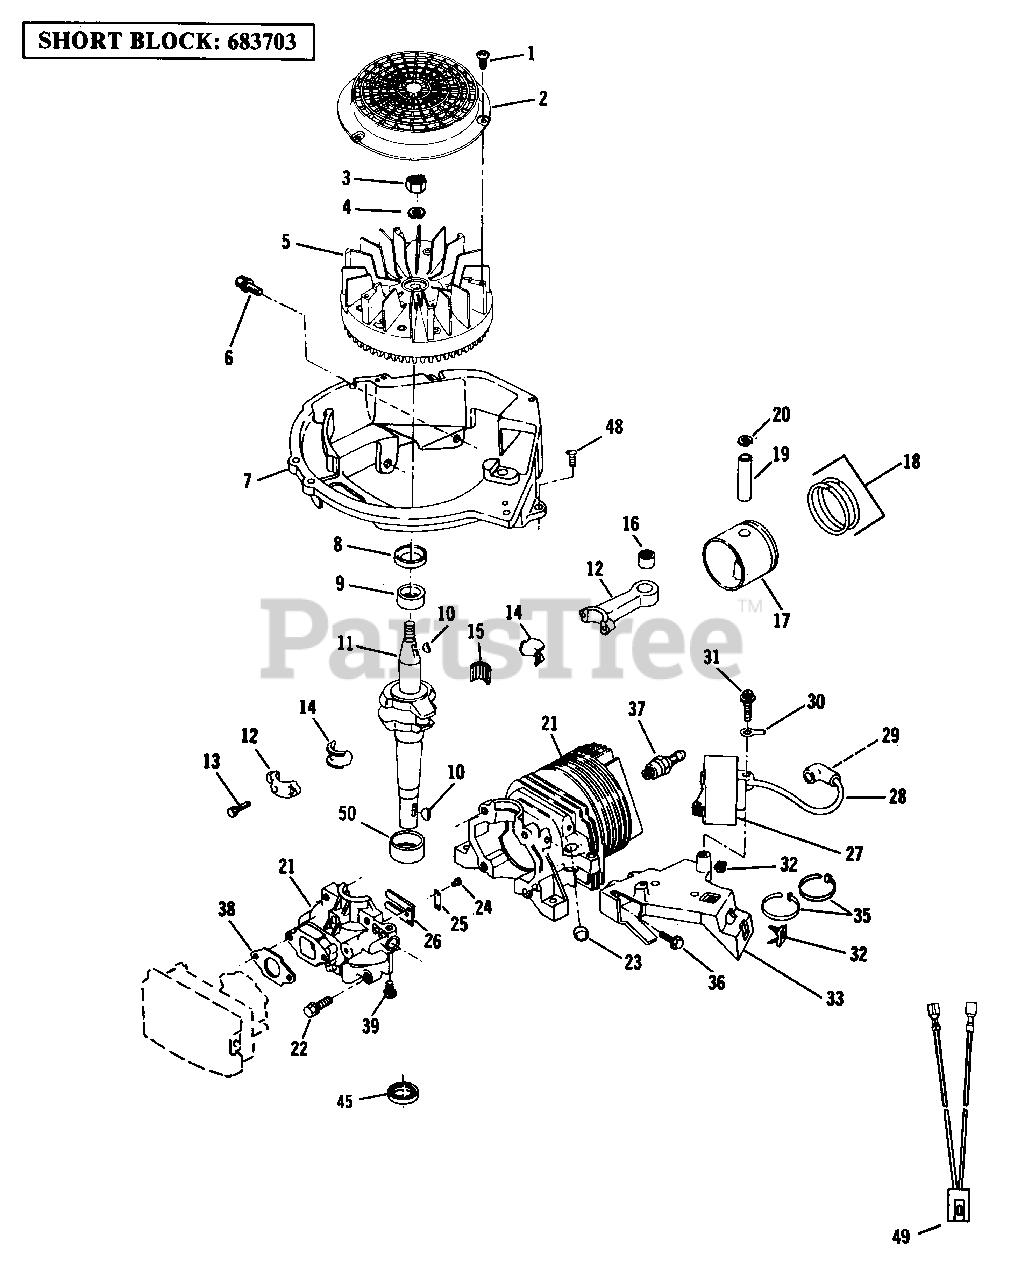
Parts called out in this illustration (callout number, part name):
1	Screw-Flywheel Screen
2	Screen-Flywheel
3	Nut-Flywheel
4	Lockwasher
5	Flywheel Assembly
6	Screw
7	Base-Shroud
8	Oil Seal-Upper
9	Bearing-Upper
10	Key-Flywheel and Clutch
11	Crankshaft
12	Connecting Rod Assembly
13	Screw Lever
14	Liner-Split
15	Needle Bearing Set
16	Bearing Assembly
17	Piston and Ring Set
18	Ring Set
19	Wrist Pin
20	Retaining Ring
21	Cylinder and Crankcase Cover Assembly
22	Screw-Cover to Crankcase
23	Plug
24	Screw-Reed to C'case Cover
25	Plate-Reed Hold Down
26	Reed
27	C.D. Ignition Module and Lead Assembly
28	High Tension Lead and Cover Assembly
29	Spring Terminal
30	Terminal-Ground Lead
31	Screw-C.D. Mounting
32	Grommet-C.D. Bracket
33	Bracket-Ignition Mtg.
35	Tie Strap
36	Screw
37	Spark Plug
38	Gasket-Carb. to Crankcase Cover
39	Set Screw-Starter Assembly
45	Oil Seal-Crankshaft
48	Screw-Shd. Base to C.D. Brk't.
49	Wire Harness-Engine
50	Bearing-Lower
